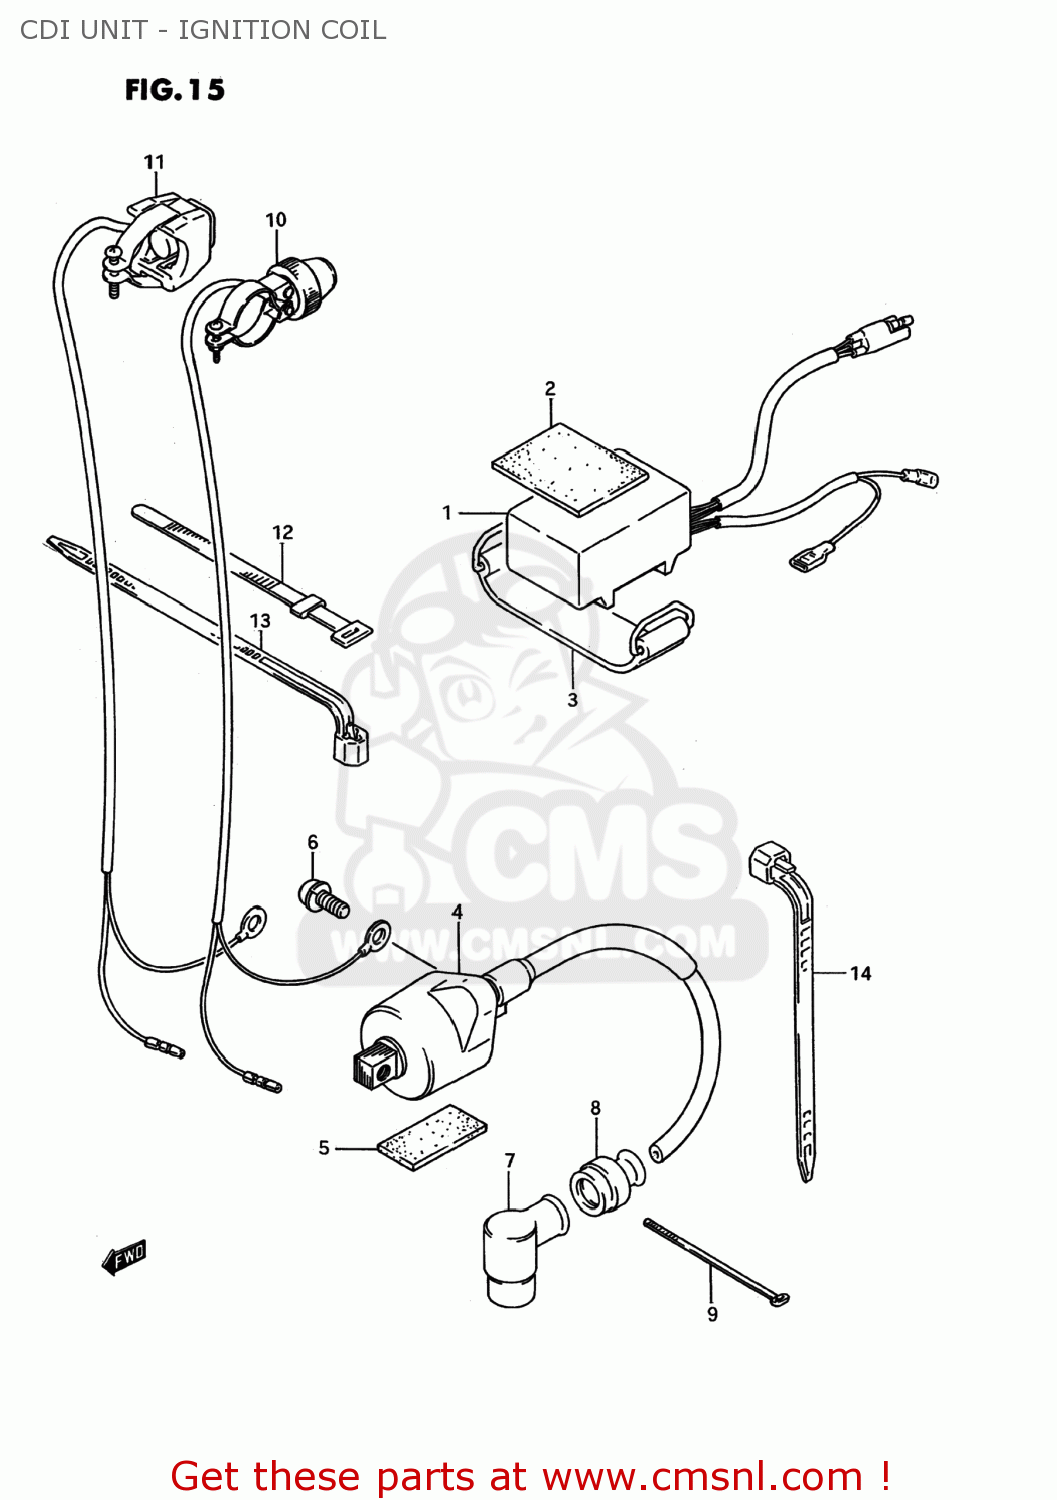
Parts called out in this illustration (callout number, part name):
1	CDI UNIT
2	PROTECTOR(170X95X3.0)
3	BAND
4	COIL ASSY,IGNITION
5	PROTECTOR,BATTERY
6	SCREW
7	CAP,SPARK PLUG
8	SEAL,HIGH TENSION CORD
9	CLAMP
10	SWITCH ASSEMBLY
11	SWITCH ASSY,ENGINE STOP
12	CLAMP(L:120)
13	CLAMP L:165
14	CLAMP(L:125)
